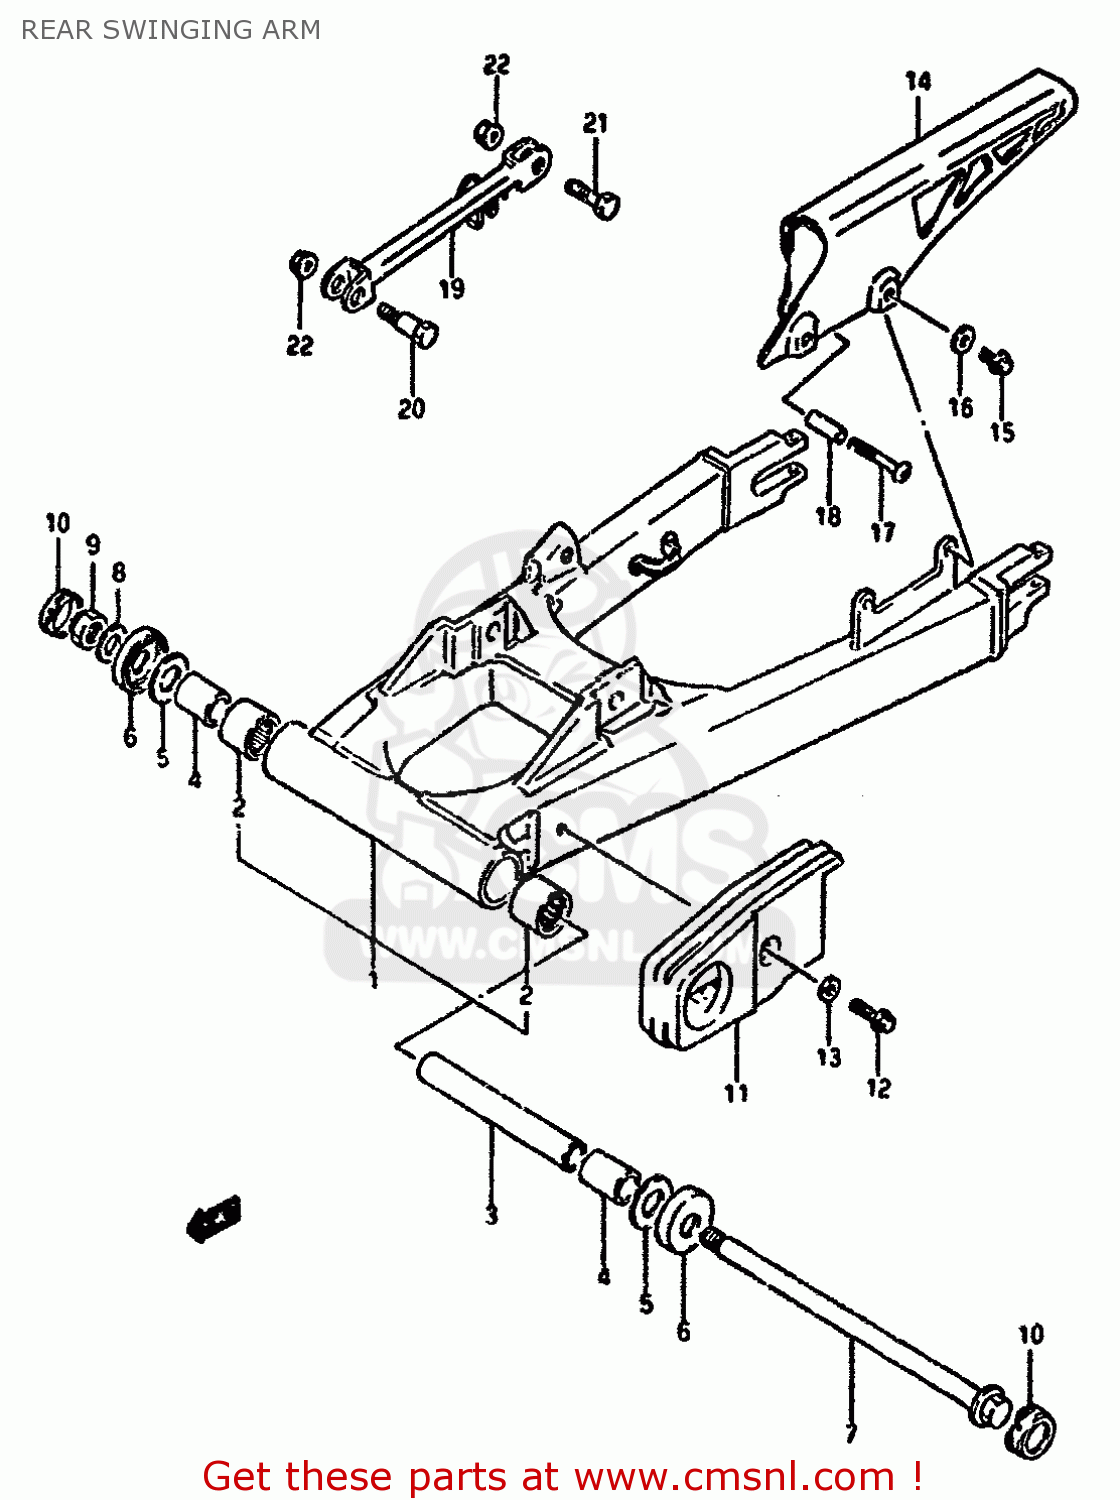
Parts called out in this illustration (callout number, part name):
1	SWING ARM ASSEMBLY,REAR
2	BEARING(25X33X30)
3	SPACER,REAR SWING ARM PIVOT
4	SPACER,RR SWGARM PIVOT
5	WASHER
6	COVER,RR SWINGINGARM PIVOT
7	SHAFT,REAR SWING ARM PIVOT
8	WASHER(14X27X3)
9	NUT
10	CAP,RR SWINGING ARM PIVOT
11	BUFFER,CHAIN TOUCH DEFENSE
12	BOLT
13	WASHER
14	CASE,CHAIN
15	BOLT
16	WASHER
17	SCREW
18	SPACER(6.5X10.5X40)
19	TORQUELINK,RR
20	BOLT,FRONT
21	BOLT,REAR
22	NUT 10MM
